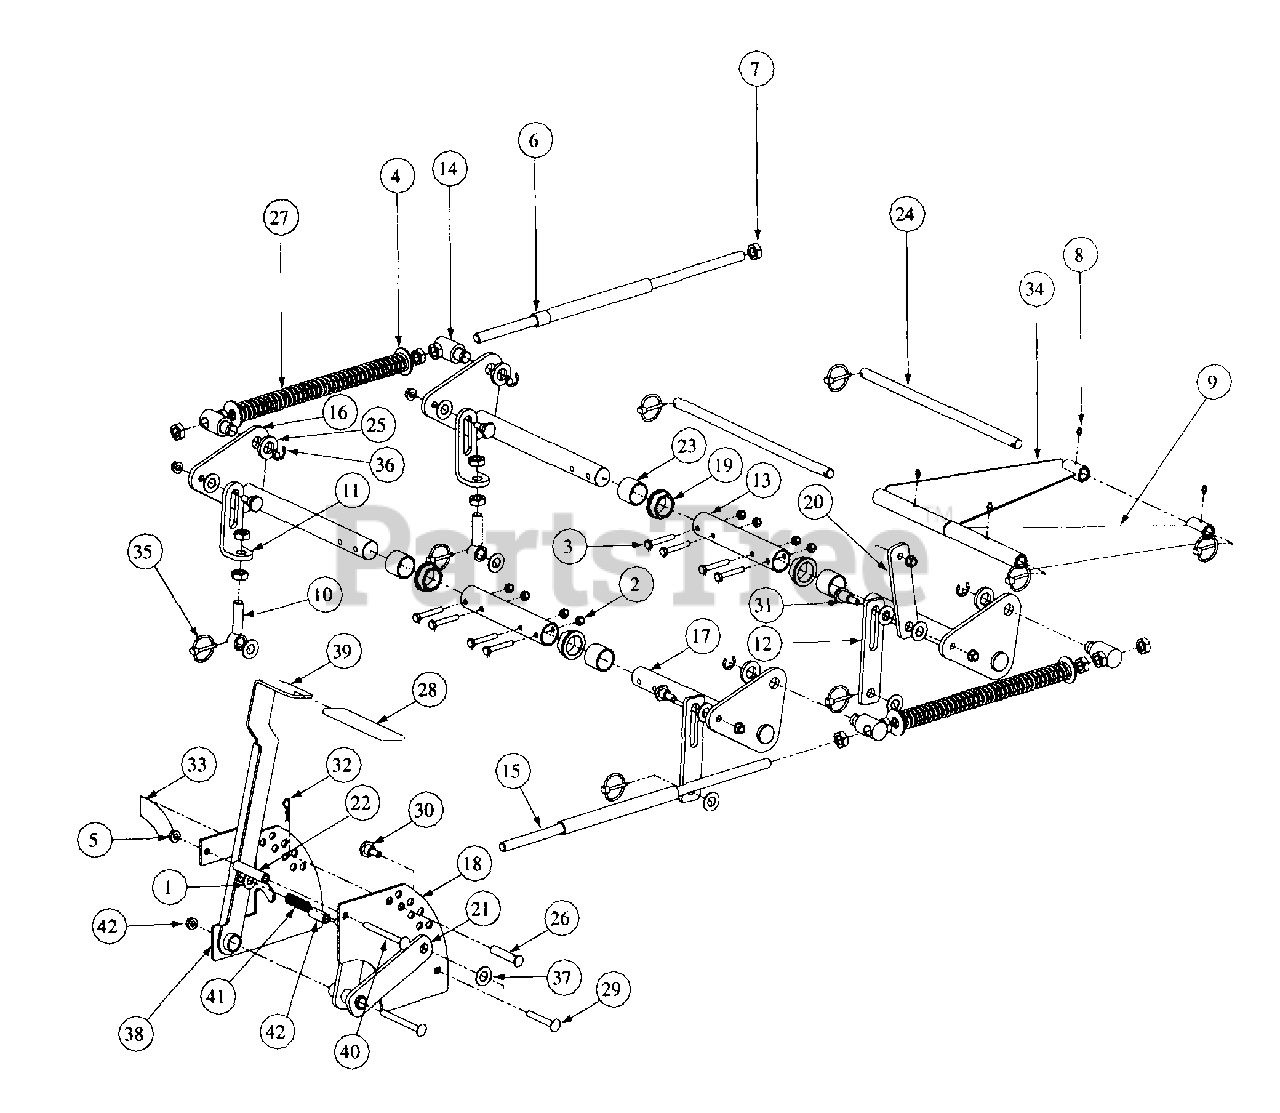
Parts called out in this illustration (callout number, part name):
1	Flat Washer, SAE, 1/2
2	Nut, 5/16-18, Nylock
3	HHCS, 5/16-18 x 2
4	Flat Washer, 5/8, USS
5	Hex Nut, 3/8-16 Flange Lock
6	Hose, 5/8" PVC, Clear Reinforced in ft.
7	Jam Nut, 5/8-11
8	Grease Fitting, 1/4-28, x 3/16
9	Brace Assembly, Right Hand Bearing Lift
10	Eye Bolt, 5/8 ID
11	Mounting Link, 5/8 ID Eye Bolt
12	Deck Link
13	Holder, Shaft Lift
14	Ferrule Lift
15	Rod, Connector Lift
16	Weldment, Bellcrank Lift Right Hand
17	Weldment, Bellcrank Lift Left Hand
18	Plate Index Lift
19	Bearing Flange, Hex, 1.25
20	Link, Lift, Index To Bellcrank
21	Weldment, Lift Handle
22	Spacer, .39 x ID x .63 OD x 2.878
23	Spacer Lift Frame
24	Rod Mount Front Lift Link
25	Spacer, .812 ID x .268 Long
26	Clevis Pin, .500 Dia. x 2.625 Long
27	Spring, Compression, Lift
28	Grip, Lift Handle
29	Carriage Bolt, 3/8-16, 2.75
30	Shoulder Screw, .625 OD x .437 Long
31	Shoulder Screw, .625 OD x .830 Long
32	Cotter Pin, .148 x 3.00
33	Decal, Height Indicator
34	Brace Assembly, Left Hand Bearing Lift
35	Linch Pin, 3/16 Dia
36	Clip E, 3/4 Dia
37	Flat Washer, 5/8 Nylon
38	Weldment, Plate, Index, Lift
39	Lift, Handle Assembly
40	Screw, Hex Cap, 3/8-16 x 3.75
41	Spring, .63 OD x 2.00 Long
42	Nut, Lock, Nylon Insert, 3/8-16
